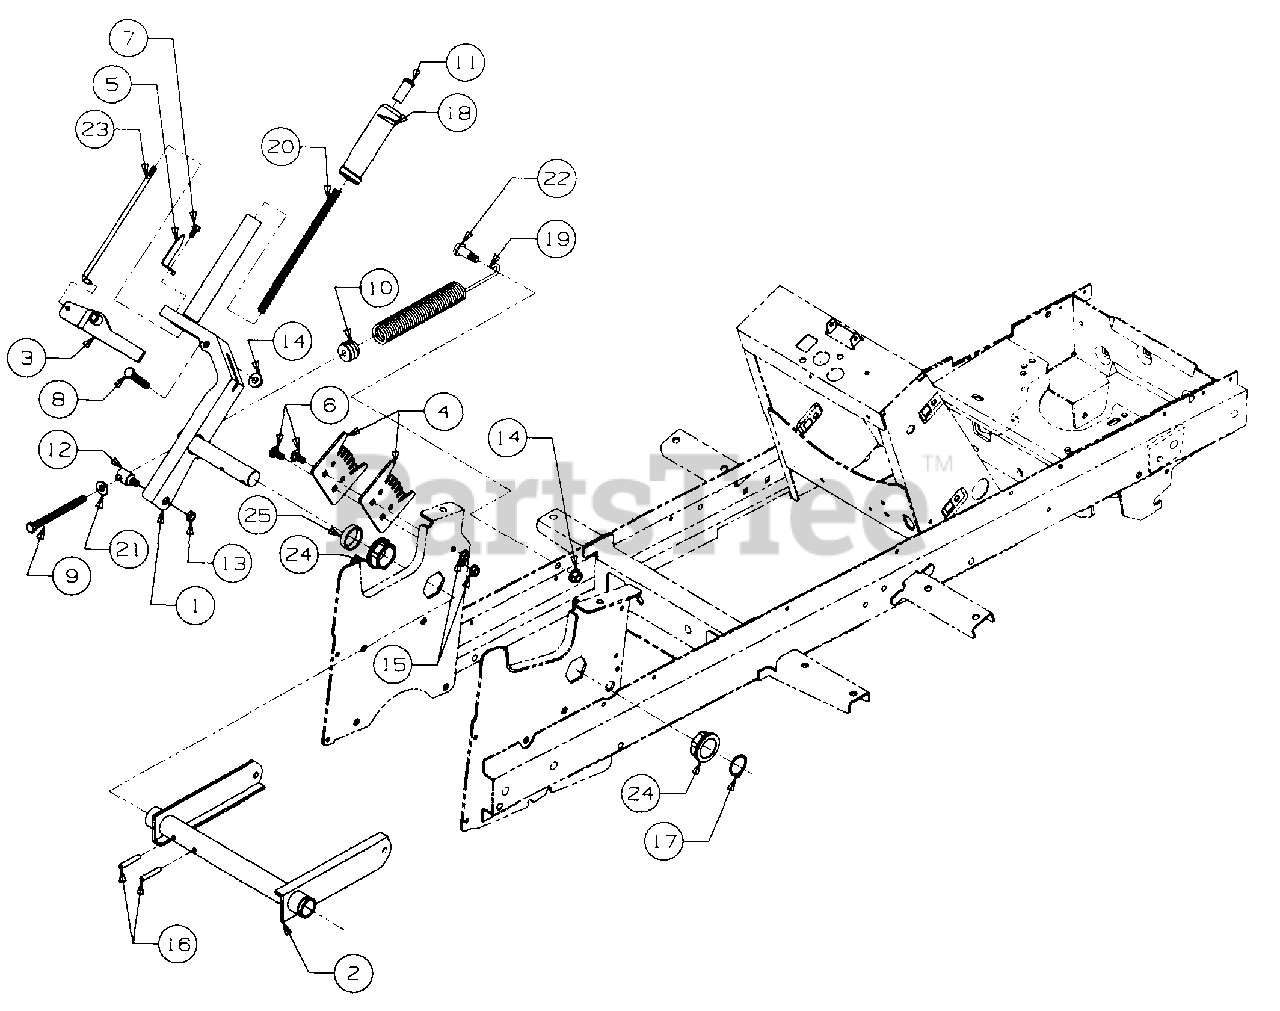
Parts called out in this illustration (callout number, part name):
3	Fork, Lift
4	Bracket, Lift Index
5	Indicator, Lift Height
6	Bolt, Carriage, 5/16 - 18 x .75 Lg
7	Screw, Hex Wash Tapp,1/4 x .50 Lg
8	Screw, Hex Cap, 3/8 - 16 x 2.0 Lg GR5
9	Screw, Hex Cap, 3/8 - 16 x 4.25 Lg GR5
10	Insert, Spring
11	Button, Handle
12	Ferrule, Adjustment
13	Nut, Hex Center Lock, Jam, 3/8 - 24
14	Nut, Hex Flanged Lock, 3/8 - 16
15	Nut, Hex Flanged Top Lock, 5/16 - 18
16	Pin, Spiral Spring, 1/4 Dia x 1.50 Lg
17	Ring, Snap,1.25 Dia Shaft
18	Grip, Lift Handle
19	Spring, Extension
20	Spring, Compression
21	Washer, Flat, .385 x .87 x .06 Thk
22	Bolt, Shoulder
23	Rod, Index
24	Bearing, Hex Flange,1.25 ID
25	Spacer, 1.28 ID x 1.5 OD x .335 Lg
